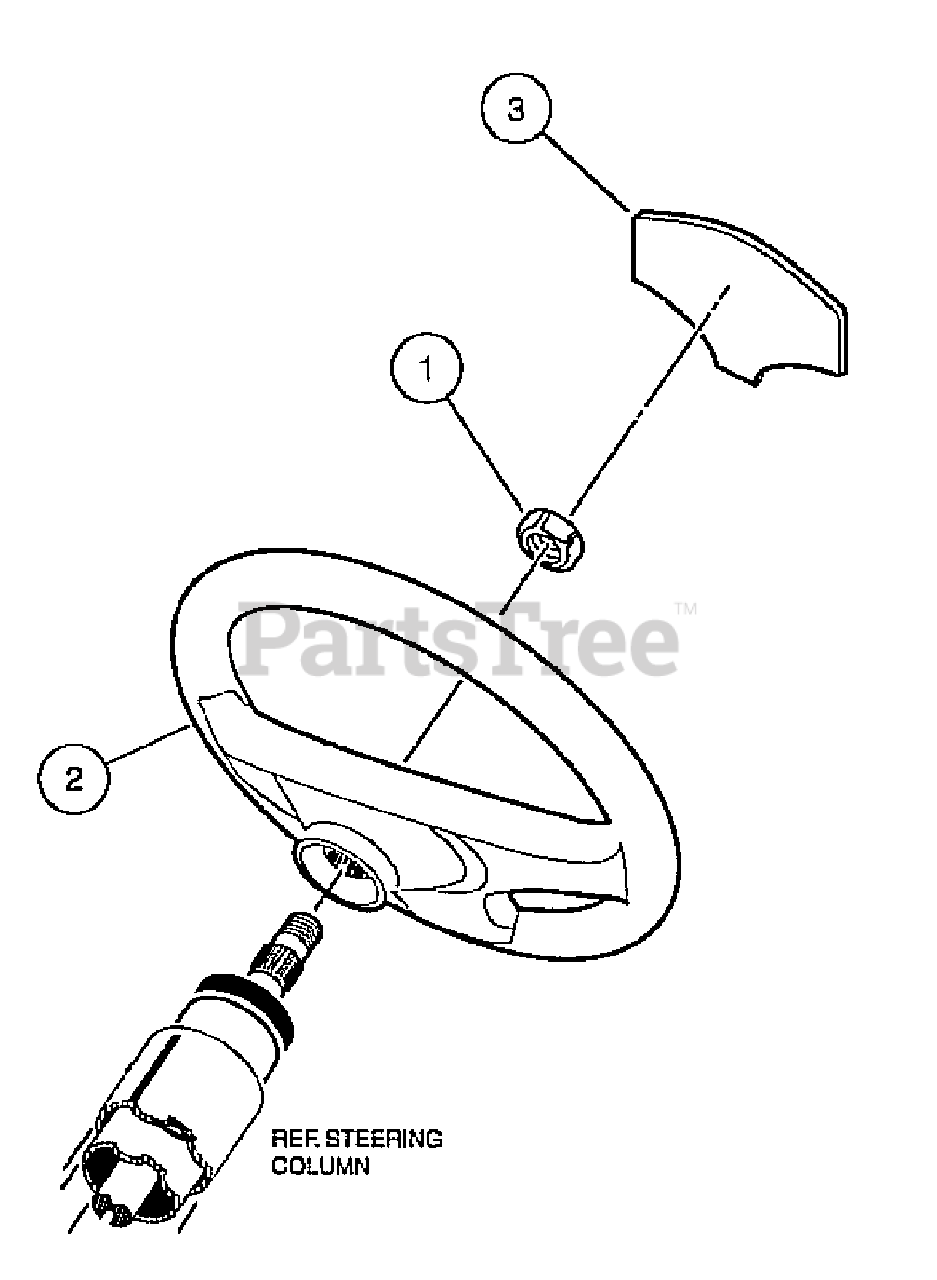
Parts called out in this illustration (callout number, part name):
1	Nut, 5/8-18 Nylon Insert Jam
2	Steering Wheel, Spline
3	Wheel Center
